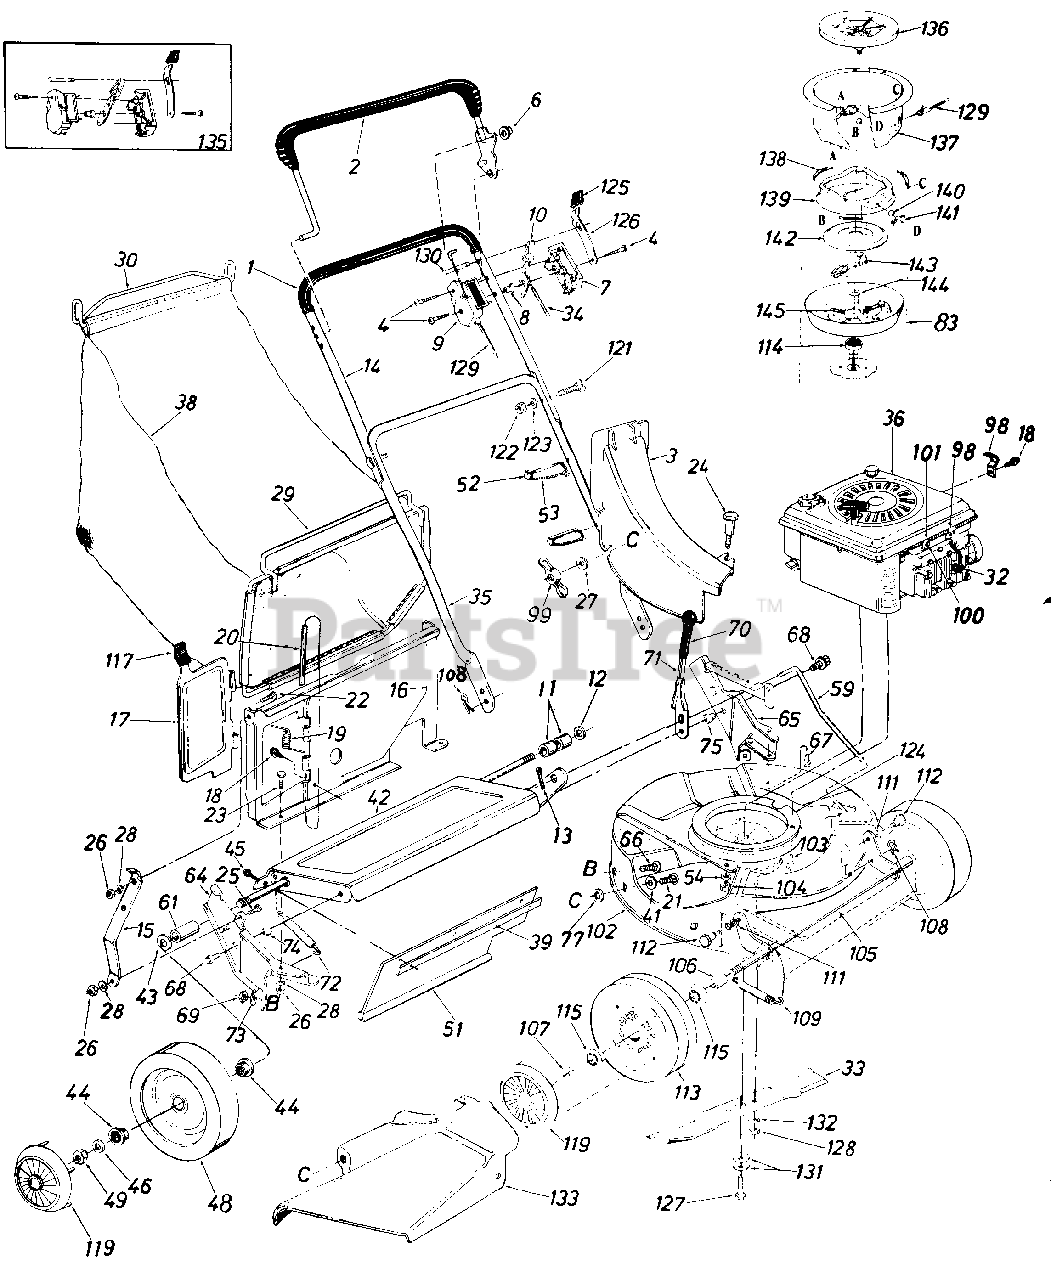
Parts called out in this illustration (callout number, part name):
2	Control Handle Ass'y.-L.H.
3	Top Discharge Chute Ass'y.
4	Truss Mach. Scr. #12 x 1.50" Lg.
6	Push Cap
7	Control Panel Half
8	Control Disc Pin
9	Clutch Panel Half
10	Throttle Control Lever
11	Spacer .526" I.D. x .690" O.D. x .640" Lg.
12	Fl-Wash. .531 I.D. x .930" O.D.
13	Cotter Pin 3/32" Dia. x.75" Lg.
14	Upper Handle-Chrome
15	Panel Support Brkt.
16	Top Catcher Panel
17	Top Door
18	Hex "B" Tap Scr. #10 x .38" Lg.
19	Torsion Spring .20" I.D. x 1.14" Lg.
20	Pivot Pin .187" Dia. x 7.25" Lg.
21	Carriage Bolt 1/4-20 x .62"*
22	Truss Mach. Scr. 1/4-20 x .50"
23	Hex Bolt 1/4-20 x .50" Lg.
24	Shld. Bolt .312" Dia. x .18" Lg. Special
25	Truss Mach. Scr. 1/4-20 x .62" Lg.
26	Hex Nut 1/4-20 Thd.
27	Fl-Wash. .280" I.D. x .620" O.D.
28	L-Wash. 1/4" kD.
29	Front Grass Catcher Framet
30	Grass Catcher Handle
32	Spark Plug Insulator
33	21" Blade
34	Throttle Control Wire 58"
35	Lower Handle-Chrome
36	Engine
38	21" Top Discharge Grass Bag
39	Retaining Strip
41	Fl-Wash. .344" I.D. x .62" O.D.
42	Rear Axle Ass'y.
43	Fl-Wash. .531" I.D. x .930" O.D.
44	Flange Ball Bearing 1/2" I.D.
45	Hex AB-Tap Scr. 1/4 x .62"
46	Fl-Wash. .531" I.D. x .9301" O.D.
48	Rear Wheel Ass'y.-Comp. 8 x 1.75
49	Hex L-Nut 1/2-20 Thd.
51	Rear Flap 3.75" x 17.30 Lg.
52	Cable Anchor
53	Cable Tie
54	L-Wash. 1/4" I.D.
59	Height Adj. Rod
61	Spacer .513" x .703"
64	R.H. Handle Wheel Brkt. Ass'y.
65	L.H. Handle Wheel Brkt. Ass'y.
66	Carriage Bolt 5/16-18 x .62"
67	Hex Wash. Hd. B-Tap Scr. 5/16-18
68	Hex Wash. Hd. TT-Tap Scr. 3/8-16
69	Hex Nut 5/16-18 Thd.
71	Height Adj. Lever
72	Extension Spring .50" O.D. x 3.80" Lg.
73	Bell-Wash. .345" I.D. x .88" O.D.
74	Spacer .385" I.D. x .502" O.D. x .270" Lg.
75	Shld. Spacer .500" Dia. x . 1.00
77	Bolt Retainer 1/4 x .50" O.D.
83	Clutch Blade Housing Ass'y.
98	Throttle Control Cable Clip
99	Wing Nut
100	Hex B-Tap Scr. #10 x .62" Lg.
101	Casing Clamp
104	Speed Nut 1/4-20 U-Type
105	Front Axle Ass'y.
106	Sleeve .526" I.D. x .690" O.D. x .880" Lg.
107	Hex L-Nut 1/2-20 Thd.
108	Intern. Cotter Pin 5/16" Dia.
109	Extension Spring .50" O.D. x 3.20" Lg.
111	Intern. L-Wash. 3/8 x .56" O.D.
112	Shld. Bolt .623" Dia. x .425
113	Front-Wheel Ass'y. Comp. 7 x 1.75
114	Ball Brg. .669" I.D. x 1.574"
115	Flange Ball Bearing 1/2" I.D.
117	Door Grip x 2.5t
119	Hub Cap-Plastic
121	Curved Carr. Bolt 5/16-18 x 1.38" Lg.
122	Hex Nut 5/16-18 Thd.
123	L-Wash. 5/16" I.D.*
124	Blade Brake Clutch Comp.
125	Spring Lever Knob
126	Lockout Spring
127	Hex Cent. L-Bolt 3/8-24 x 2.00" (Grade 8)
128	Hex Nut 3/8-24 Thd. (Grade 8)
129	BBC Clutch Cable-46"
130	Lock Pin .314" Dia. x 1.75"
131	Bell-Wash. .400" I.D. x .88" O.D.
132	L-Wash. 3/8" I.D.
133	Side Chute Deflector
135	Kit-Control Housing Comp.
136	Fan Adapter
137	Clutch Housing
138	Extension Spring .35" O.D. x 1.75" Lg.
139	Brake Cup Cone
140	Steel Ball .500" Dia.
141	Ball Block
142	Clutching Cone
143	Hex Tap L-Scr. 1/4-20 x .75"
144	Fl-Wash. .690" I.D. x 1.060" O.D.
145	Compression Spring .35" O. D. x 2.00" Lg.
